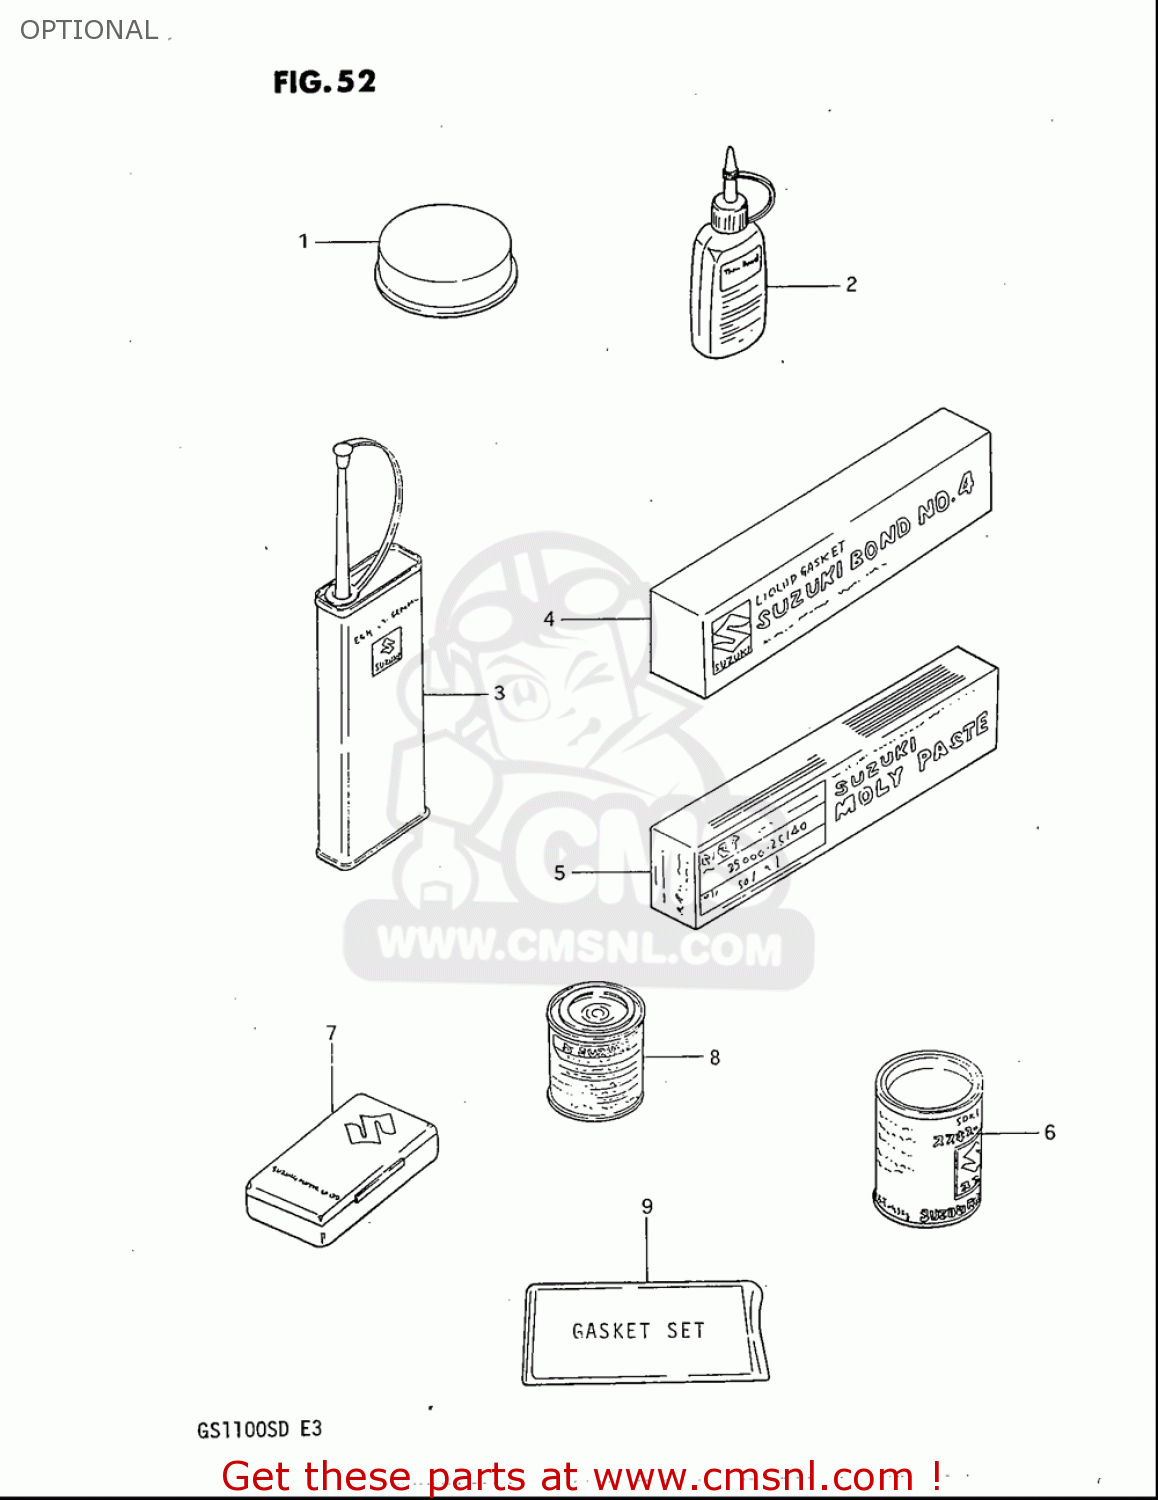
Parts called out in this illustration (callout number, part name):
1	GREASE,PBC FOR BRK PAD 20G
2	THREAD LOCK NO.1342
3	THREAD LOCK NO.1401 CLEAR 200G
4	BOND 1104
5	SUZUKI MOLY PASTE
6	GREASE(C)EP2 LITHIUM 150G
